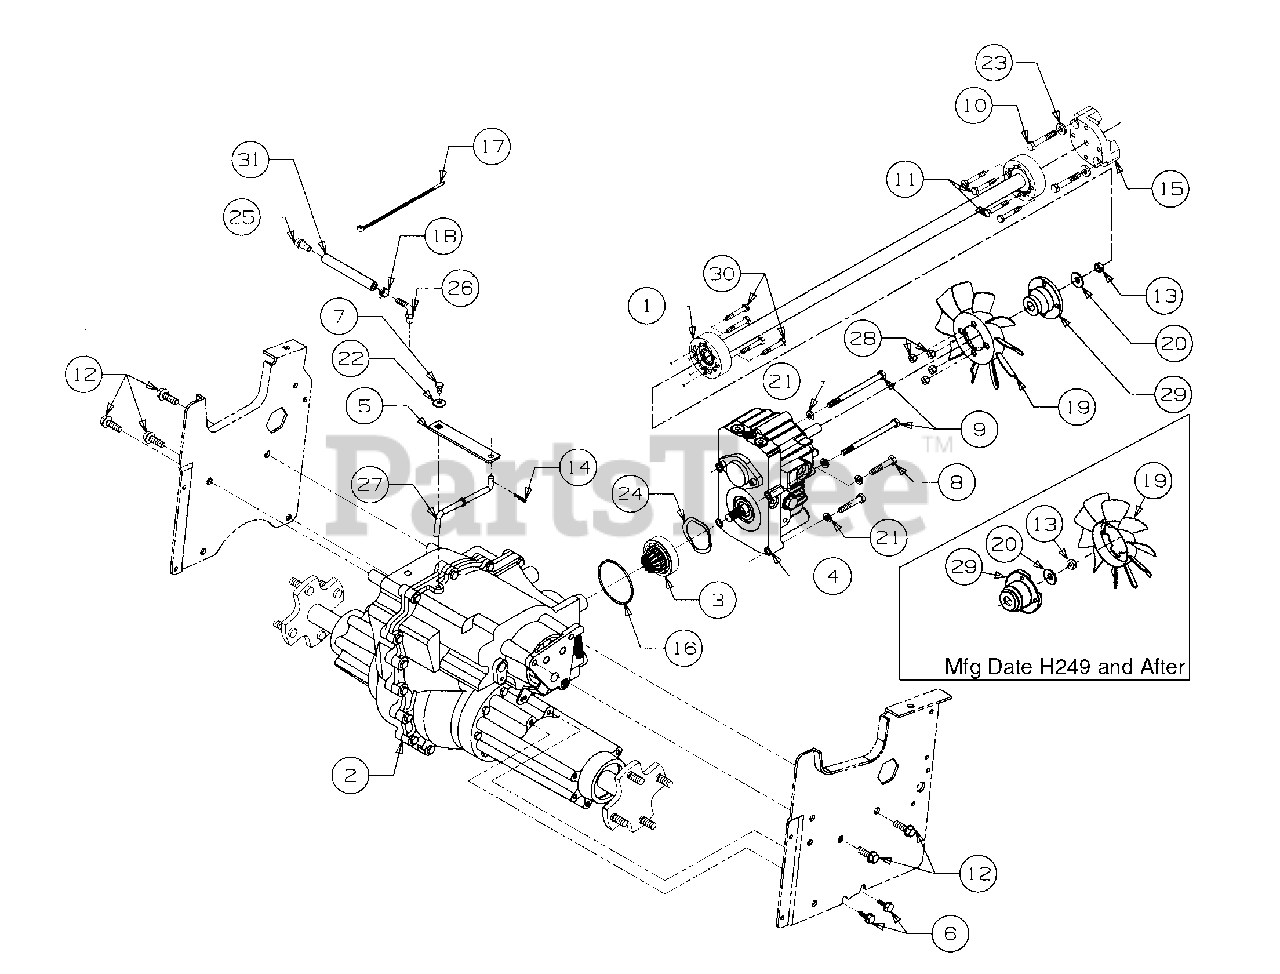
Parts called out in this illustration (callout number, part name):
1	Shaft Assembly, Drive, 29.06 Lg
2	Transmission Assembly, Hydro
3	Pinion Assembly, Input
4	Pump, Hydrostatic
5	Arm, Hydro Dump
6	Screw, Hex Wsh Hd Tap, 5/16-18 x .75
7	Screw, Hex Wsh Hd Tap, 1/4-20 x .75
8	Screw, Hex Cap, 5/16-18 x 1.75 GR5
9	Screw, Hex Cap, 5/16-18 x 4.5 GR5
10	Screw, Hex Patch, M8-1.25 x 50mm
11	Screw, Hex Patch, 1/4-20 x 1.62 GR5
12	Screw, Hex Wsh Hd Tap, 3/8-16 x 1.25
13	Nut, Hex Center Lock Jam, 3/8-24
14	Pin, Internal Cotter, 5/16 Dia x 1.12
15	Adapter, Drive Shaft
16	O-Ring, 2.75 x .103
17	Tie, Self-Clinch Cable
18	Clamp, Hose
19	Fan, 10 Blade
20	Washer, Bell, .380 x .88 x .063
21	Washer, Lock, 5/16
22	Washer, Bell, .265 x .75 x .062
23	Washer, Flat, .312 x .750 x .119
24	Washer, Sprg, Wave, 1.96 x 2.44 x .06
26	Fitting, Elbow
27	Rod, Hydro Disengagement
28	Nut, Fan, 1/4-20
29	Adapter, Pump
30	Screw, Hex Patch, 1/4-20 x 1.62 GR5
